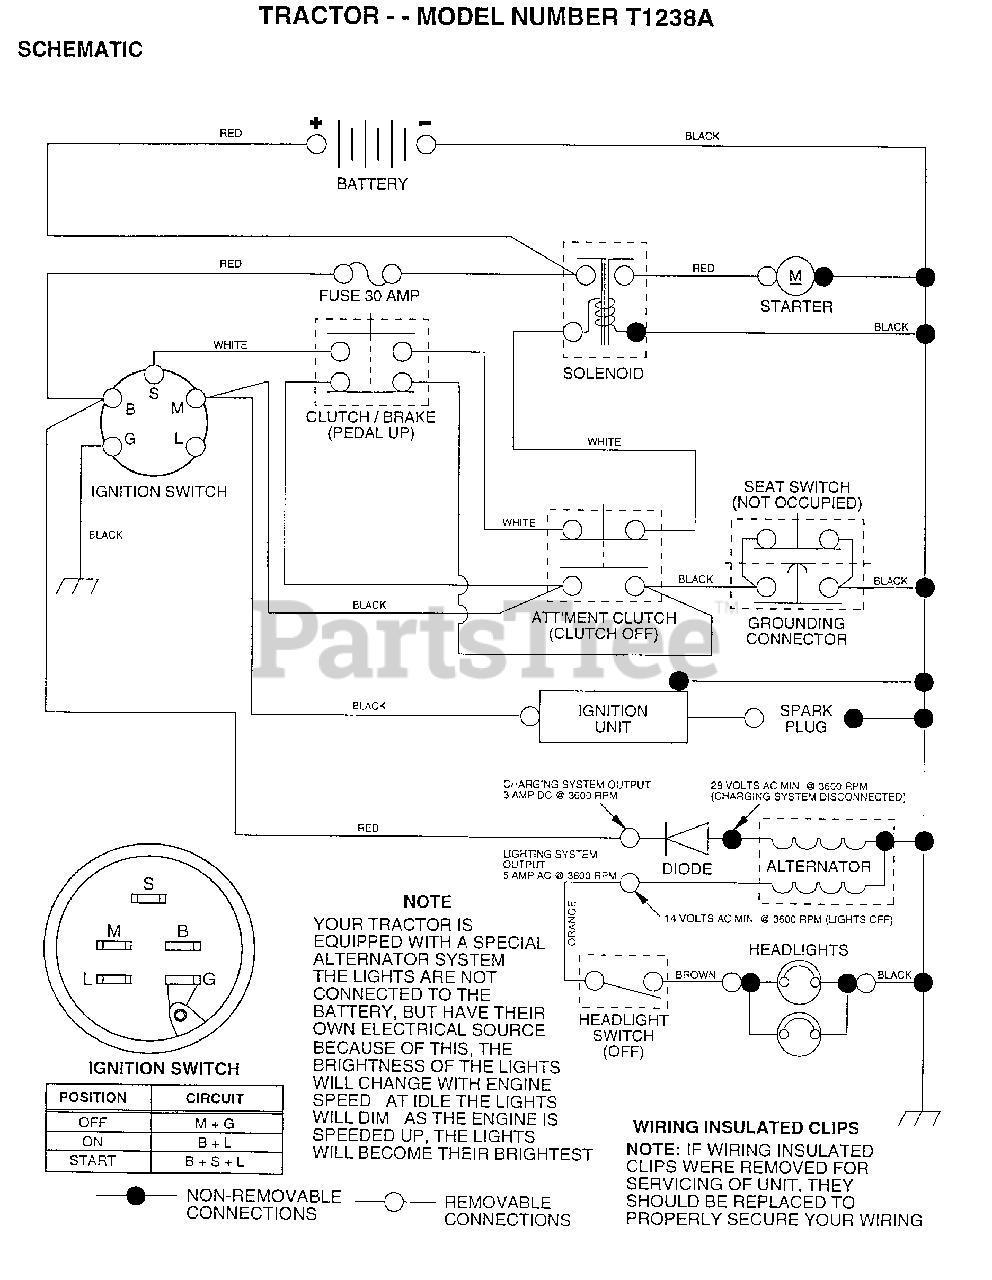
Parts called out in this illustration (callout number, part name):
1	DECAL.DASH.INSTR.
1	VALVE CAP
2	"DECAL,GRILL"
2	VALVE STEM LT
3	DECAL, HP ENGINE
4	DECAL GRILLE COOP
4	TUBE.5.3/4.5/6
5	"RIM ASM 6"" FRT"
6	DECAL CAUTION
6	FITTING LT
7	DECAL T
7	"FLANGE, BEARING"
8	DECAL LOGO FENDER
8	"RIM AS 8"" REAR"
9	DECAL.STRIPE.GR
10	TUBE.18X9.5-8
11	"DECAL, WARNING"
11	HUB CAP
12	DECAL HOOD RH
13	"DECAL,STR WHL T"
14	DECAL HOOD LH
15	DECAL.BTRY.DANGER
16	DECAL BRAK PARK
17	DECAL
